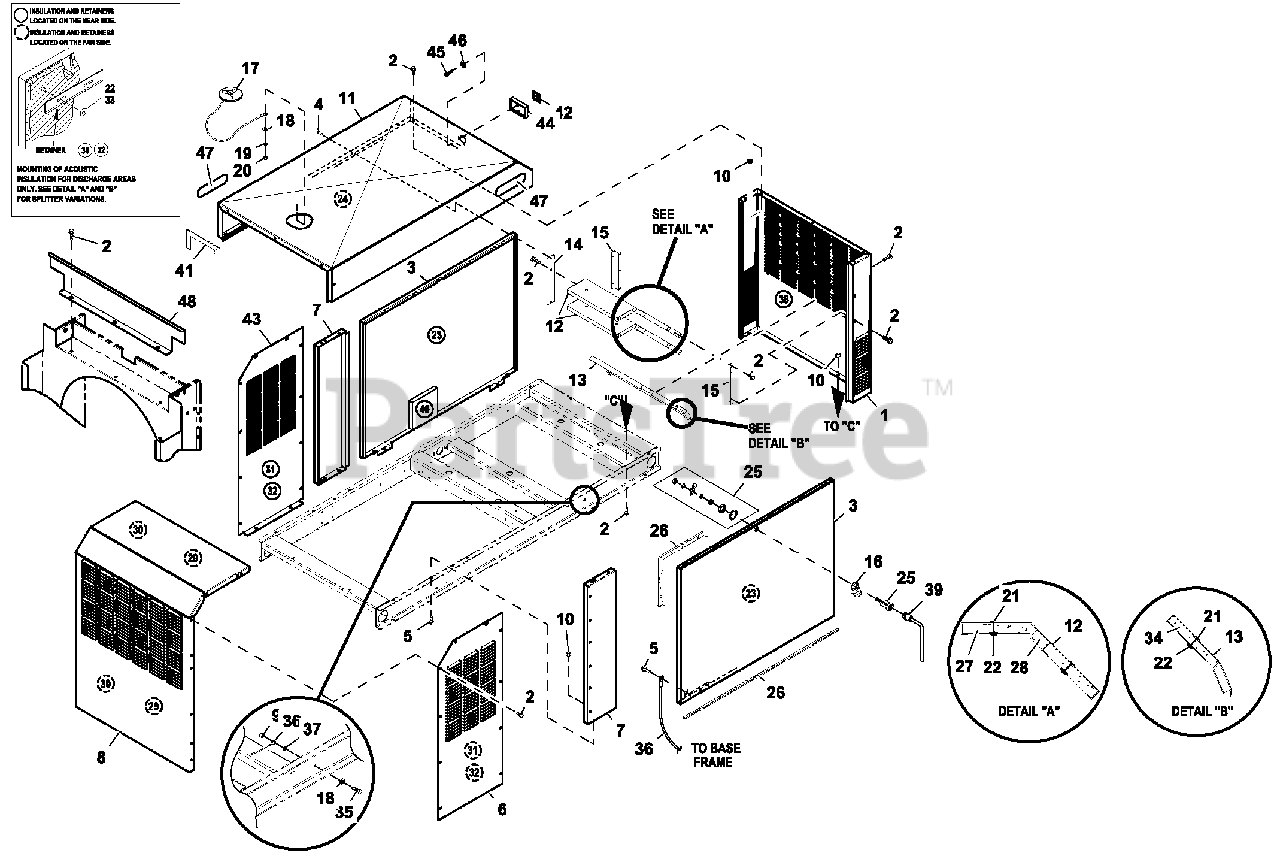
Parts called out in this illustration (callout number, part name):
1	REAR WRAP C2 CPL
2	SCREW THFM6-1 X 16 N WA Z/JS
3	DOOR C2
4	RIVET POP .1875 X .450 SS
5	SCREW TH-FRM M6 W/CAP SHKPRF W
6	DUCT DISCHARGE LH C2 AL
7	FRONT CORNERS C2
8	DUCT DISCHARGE MID C2
9	NUT HEX M6 X 1.0 G8 YEL CHR
10	NUT HEX LOCK M6-1.0 SS NY INS
11	ROOF C2 CPL PVT LBL
12	SLITTER C4
13	SPLITTER LOWER C4
14	SPLITTER STRINGER C2
15	SUPPORT SPLITTER LH C2
16	TAB PULL
17	ASSEMBLY COVER ACCESS
18	WASHER FLAT 1/4-M6 ZINC
19	WASHER LOCK M6-1/4
20	NUT HEX 1/4-20 STEEL
21	INSULATION RETAINMENT HANGER
22	WASHER SELF LOCKING D OME #4-40
23	INSULATION D OOR C2
24	INSULATION ROOF TOP
25	VISE-ACTION LATCH SLOTTE D CIR
26	GASKET EXTRUDE D TRIM (328" LG)
27	INSULATION SPLITTER
28	INSULATION SPLITTER
29	INSULATION DUCT
30	RETAINER INSULATION (820)
31	INSULATION DUCT SIDES
32	RETAINER INSULATION (450)
33	WASHER SELF LOCKING D OME #8-32
34	INSULATION LOWER SPLITTER
35	SCREW HHC M6-1.0 X 20 G8.8
36	ASSY WIRE 14AWG 34.8" GRN/YEL
37	WASHER SHAKEPROOF INT 1/4
38	INSULATION REAR WRAP
39	KEY VISE-ACTION LATCH SLOT CIR
40	FOAM 300 X 300 THERMAL ACO (APPLIES TO 4.2L UNITS ONLY)
41	STRIP SEALANT 1/8X 1 (44.52"LG)
42	RF COVER PLATE-PLASTIC- DRK GRY (OPTIONAL)
43	DUCT DISCHARGE RH C2 AL
44	ASSY ENCLOSURE GEN SI DE RF
45	SCREW PPPH M3X 12
46	WASHER FLAT M3
47	BA D GE, HONEYWELL
48	BAFFLE TOP EXHAUST C2 HW
